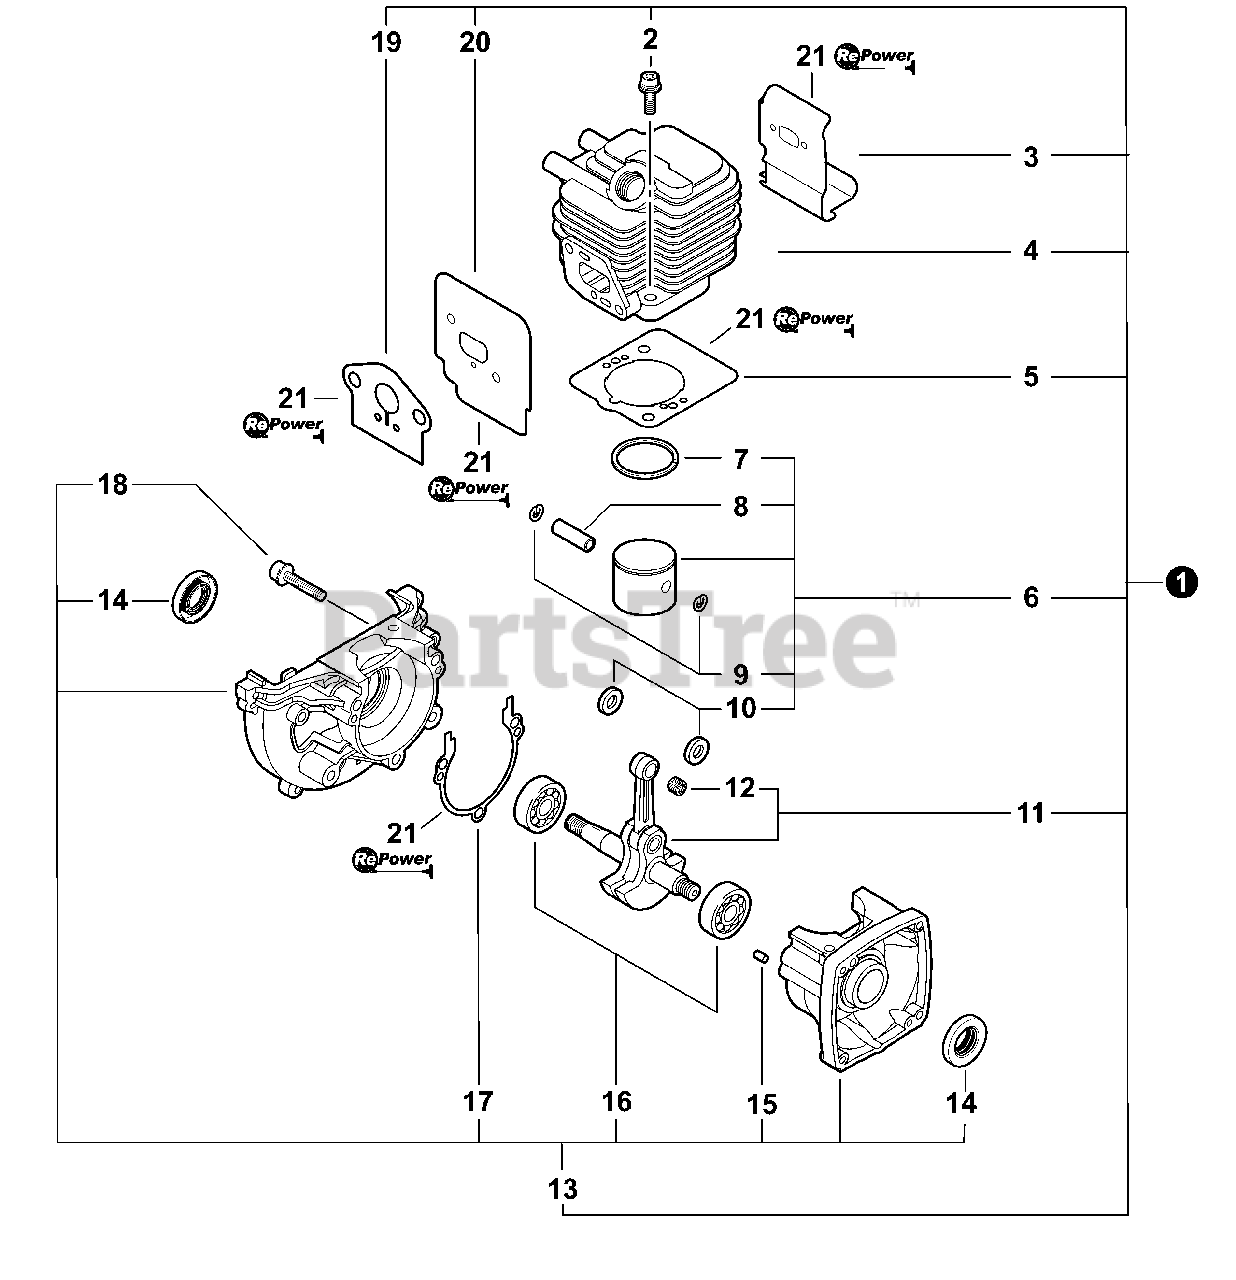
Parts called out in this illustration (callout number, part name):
1	SHORT BLOCK
2	BOLT 5×22
3	HEAT SHIELD, EXHAUST
4	CYLINDER
5	GASKET, CYLINDER
6	PISTON KIT
7	RING, PISTON
8	PIN, PISTON 8
9	RING, SNAP
10	WASHER, THRUST
11	CRANKSHAFT ASSY
12	BEARING, NEEDLE 8
13	CRANKCASE KIT
14	SEAL, OIL 12
15	PIN, LOCATING 4×8
16	BEARING, BALL - 6201 C3
17	GASKET, CRANKCASE
18	BOLT 5×28
19	GASKET, INTAKE
20	HEAT SHIELD, INTAKE
21	GASKET KIT
